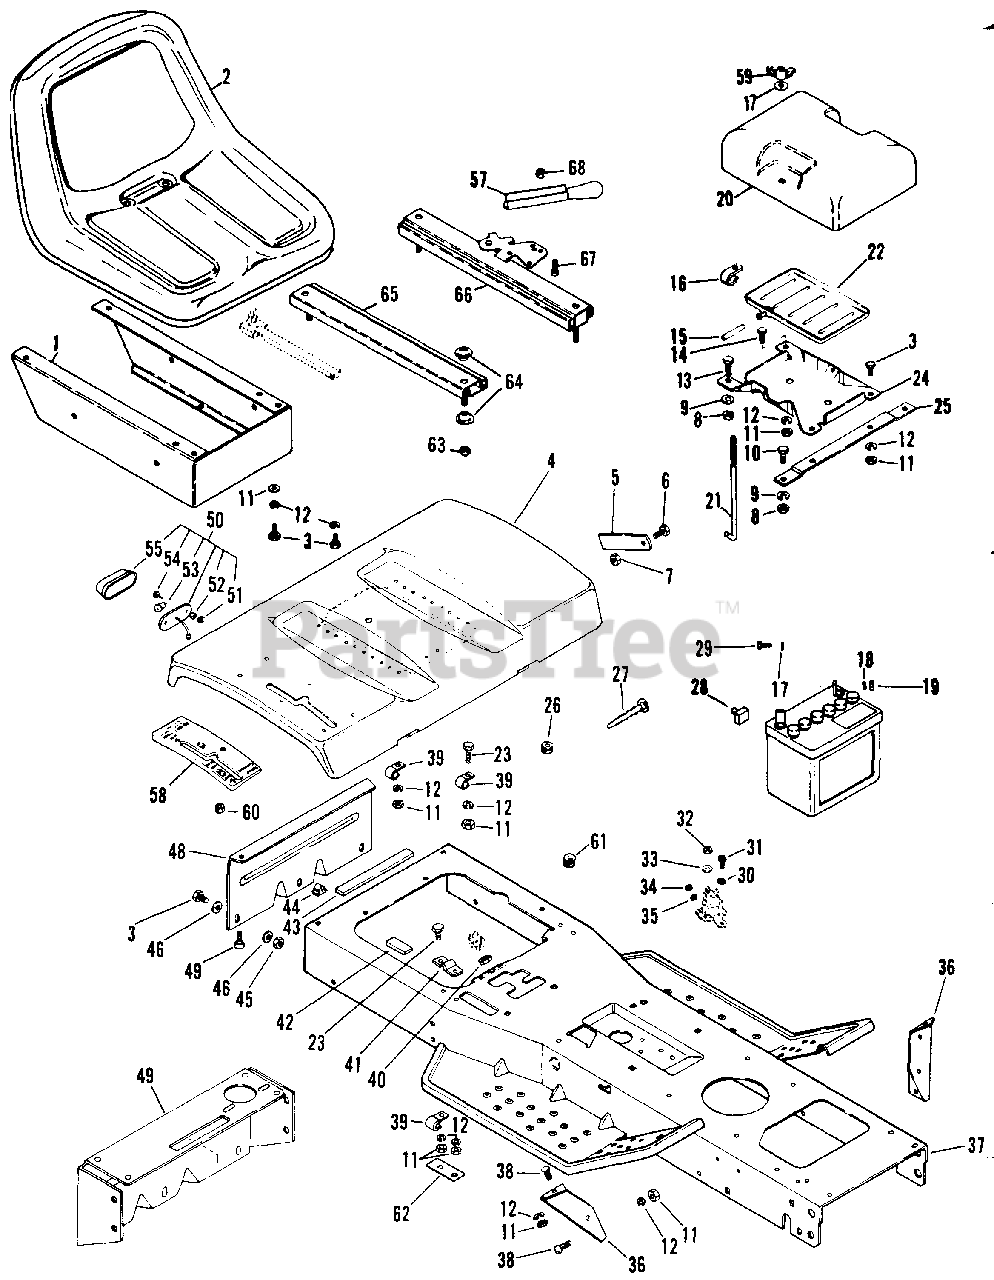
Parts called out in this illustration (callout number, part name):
1	FRAME, SEAT
2	SEAT
3	BOLT, HEX 5/16-18X.75
4	DECK, REAR
5	CATCH, DECK
6	BOLT, HEX 3/8-16X.625
7	NUT, LOCK 3/8-16
8	NUT, HEX 3/8-16
9	WASHER, LOCK 3/8 REG.
10	BOLT, HEX 3/8-16X.75
11	NUT, HEX 5/16-18
12	WASHER, LOCK 5/16 SP.
13	BOLT, HEX 3/8-16X1.25
14	BOLT, HEX 5/16-18X1.00
15	HOSE, DRAIN
16	J-CLAMP
17	WASHER, FLAT .281X.625X.065
18	WASHER, LOCK 1/4 REG.
19	NUT, HEX 1/4-20
20	COVER, BATTERY
21	BOLT, HOLD DOWN
22	TRAY, PLASTIC BATTERY
23	BOLT, HEX 5/216-18X.75
24	TRAY, BATTERY
25	STRAP
26	GROMMET
27	TIE DOWN
28	INSULATOR(RED)
28	INSULATOR(BLACK)
29	BOLT, HEX 1/4-20X.875
30	WASHER, LOCK 1/4 EXT. TYA
31	SCREW, TAPTITE 1/4-20X.375
32	NUT, JAM 5/16
33	WASHER, LOCK 5/16 INT. TOOTH
34	NUT, HEX 10-32
35	WASHER, LOCK #10 EXT.
36	STRUT, L.H. FOOTBOARD
36	STRUT, R.H. FOOTBOARD
37	FRAME, MAIN
38	BOLT, CARRIAGE 5/16-18X.75
39	J-CLAMP
40	NUT
41	BRACE
42	TAPE, FOAM
43	TAPE, FOAM
44	BUMPER
45	NUT, LOCK 5/16-18
46	WASHER, FLAT .406X.812X.065
47	NUT, LOCK 3/8-16
48	DRAWBAR
49	BOLT, HEX 3/8-16X1.25
50	ASSEMBLY, TAIL LIGHT
51	NUT, 10-24 HEX
52	WASHER, LOCK NO. 10 SP.
54	SCREW, MACHINE 10-24X.50 PHD
55	LENS
56	BUSHING, SPACER
57	HANDLE, SEAT ADJUSTER
58	INSERT, SHIFT
59	NUT, WING 1/4-20
60	NUT, SELF THREADING
61	PLUG, HOLE
62	STRAP
63	NUT, LOCK 5/16-18
64	SPACER
65	ADJUSTER, SEAT
66	ADJUSTER, SEAT W/LATCH
67	SCREW, MACHINE 10-24X.625 PHD
68	NUT, LOCK 10-24
NS	DECAL, TRACTOR
NS	DECAL, AMERICA
NS	DECAL, GRAVELY LOGO
NS	DECAL, BRAKE LOCK
NS	DECAL, FAN
NS	DECAL, TRANSMISSION DISCONNECT
